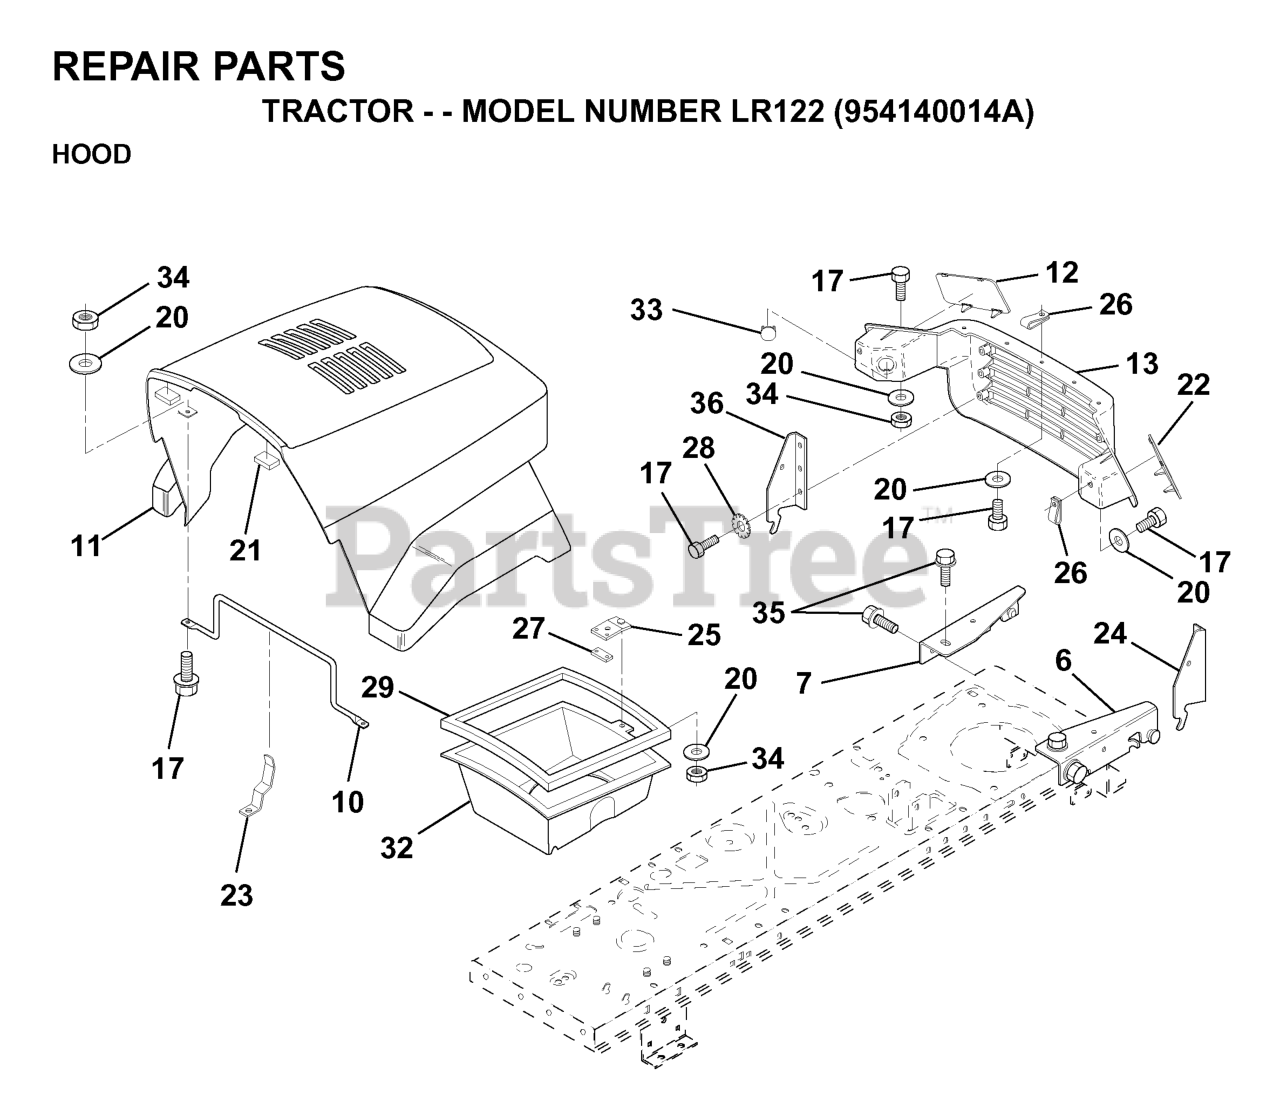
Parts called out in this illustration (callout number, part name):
6	BRACKET ASSY HOOD
7	BRACKET ASSY
10	BRACE HOOD
11	HOOD
12	LENS/LH
13	GRILLE
17	BOLT
21	BUMPER HOOD T
22	LENS
23	HOOD LATCH
24	BRACKET PIVOT
26	CLIP TINNERMAN
28	Washer, Lock, External Tooth 1/4
29	FOAM STRIP LT
33	CVR LIGHT SOCKET
34	NUT.CROWNLOCK.1/4
35	SCREW.THDROL.5/16-18X3/4.TTY
36	BRACKET HOOD
